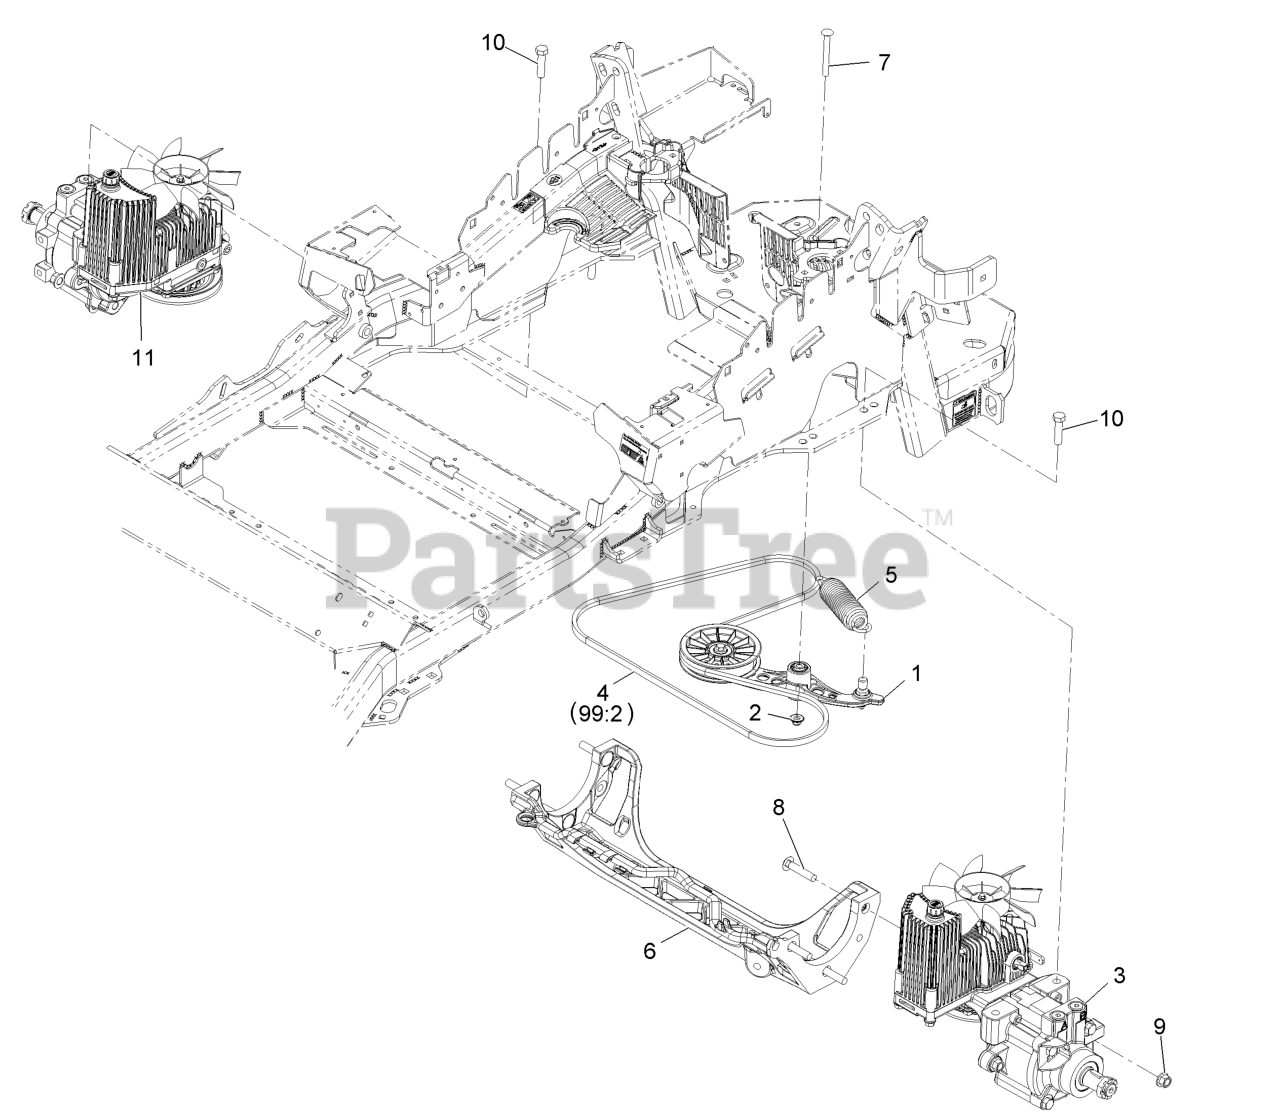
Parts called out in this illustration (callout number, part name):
1	PUMP IDLER ASM
2	Nut-Nyloc 3/8-16 Flg
4	BELT
7	BOLT-SHOULDER, CARRIAGE 3/8-16 X 3 1/2
8	SCREW-CARR
9	Nut-Lock 1/2-13
10	SCREW-HH
99:2	BELT
